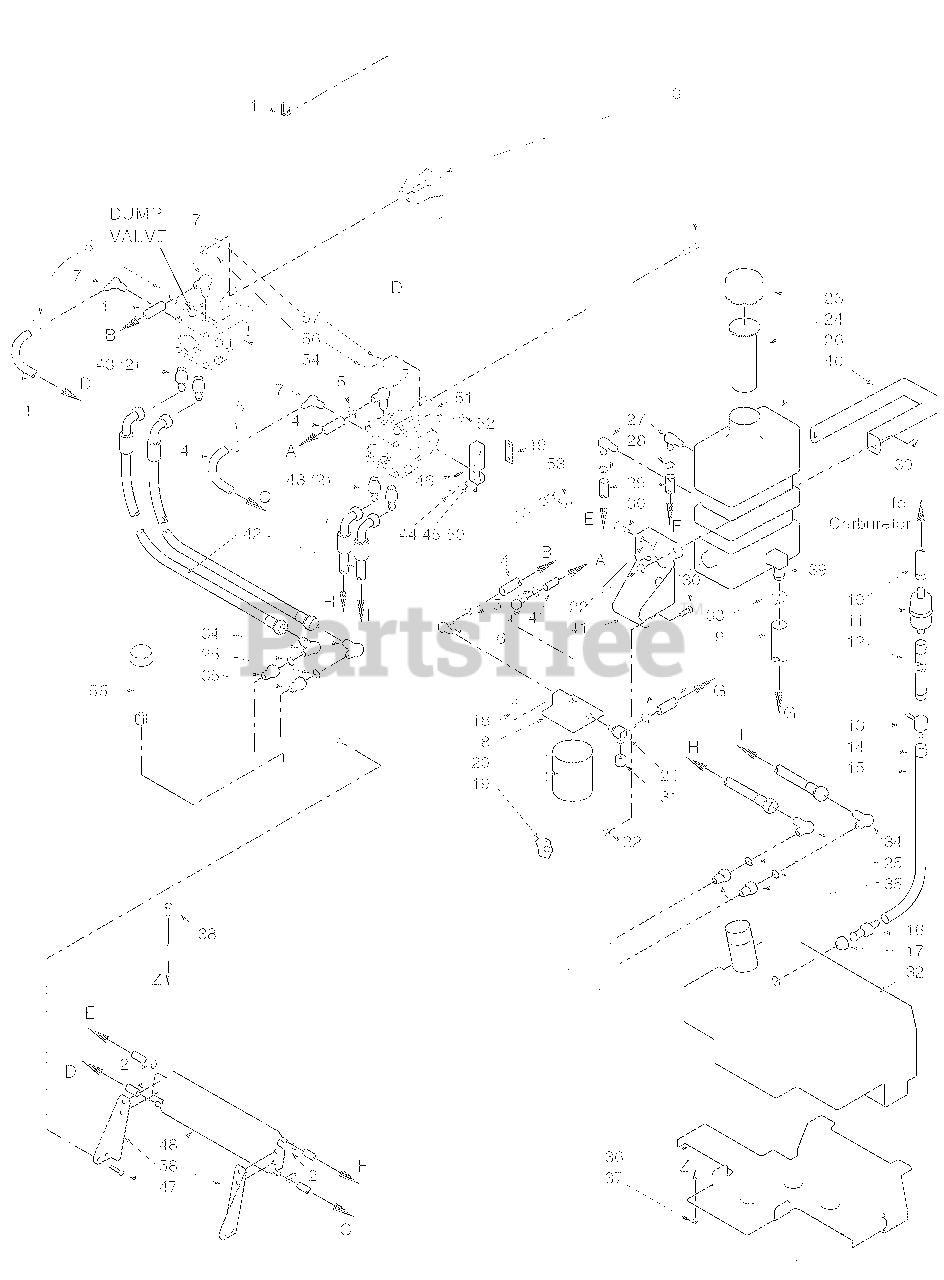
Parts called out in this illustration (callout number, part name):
1	U-Nut 1/4-20
2	Hose Clamp, 0.69 dia.
3	Bolt, Hex Head 1/4-20 x 2.0"
4	Hose, 3/8" ID Pushlock
5	Clamp, Hose 1/2"
6	Elbow, 90 Degree - 1/4 NPT x 3/8" Hose
7	Elbow, 90 Degree - 9/16 O-ring x 3/8" Hose
8	Oil Filter Base
9	Hose Assembly, 1/2" ID
10	Fuel Hose to Carb.
11	Fuel Filter
12	Fuel Hose, 1/4" ID. Non-Perm.
14	Clamp, Fuel Hose
15	Fuel Hose, 1/4" ID. Non-Perm.
16	Hose Fitting
17	Bushing
18	Bolt, Hex Head 5/16-18 x1.0" Zinc
19	Nut, Serrated Flange 5/16-18
20	Oil Filter
21	Tee, 3/4 O-ring x JIC x 1/2" Hose
22	Nut, Hex Elastic Stop 1/4-20
23	Cap, Hydraulic Tank
24	Insert, Filler Neck
25	O-Ring
26	Oil Reservoir Assembly
27	Elbow, 90 Degree .38 Hose
28	Hose Clamp, 0.69 dia.
29	Hose, 3/8" ID, Pushlock
30	Screw, Phillips Head, 1/4-20
32	Fuel Tank Assembly
33	Clamp, Hose
34	Elbow, 90 Degree, 1/2" x 1/2"
34	Elbow, 90 Degree, 5/8" x 1/2"
35	Bushing, 7/8-14 JIC x 3/4-16 O-Ring
36	Support Bracket, Fuel Tank
37	Nut, 5/16-18 Serrated Flange
38	Bolt, Carraige 1/4-20 x 3/4"
39	Elbow, 90 Degree
40	Strap, Hydraulic Tank
41	Support Bracket, Hydraulic Tank
42	Hose Assembly, Pump
43	Union, 3/4-16 JIC x 3/4-16 O-ring
44	Bolt, Hex Head, 1/4-20 x 1-1/4"
45	Lockwasher, 1/4" Spring
46	Roll Pin, Spring 3/16 x 3/4"
47	Bolt, Hex Head 5/16-18 x 3/4"
48	Cooler, Oil
49	Clamp Plate, Pump Control
50	Block, Pump Control
51	Pump, Left Hand, BDP-16A-410
51	Pump, Left Hand, BDP-16A
52	Nut, Hex, Elastic Stop 3/8-16
53	Bolt, Hex Head, 3/8-16 x 1-1/4
54	Pump, Right Hand, BDP 16A-307
54	Pump, Right Hand, BDP-16A
55	Cap, Fuel Tank W/Gauge
56	Nut, Hex Elastic Stop 3/8-16
57	Flatwasher, 3/8" Grade 8
58	Mounting Bracket - LH, Oil Cooler
